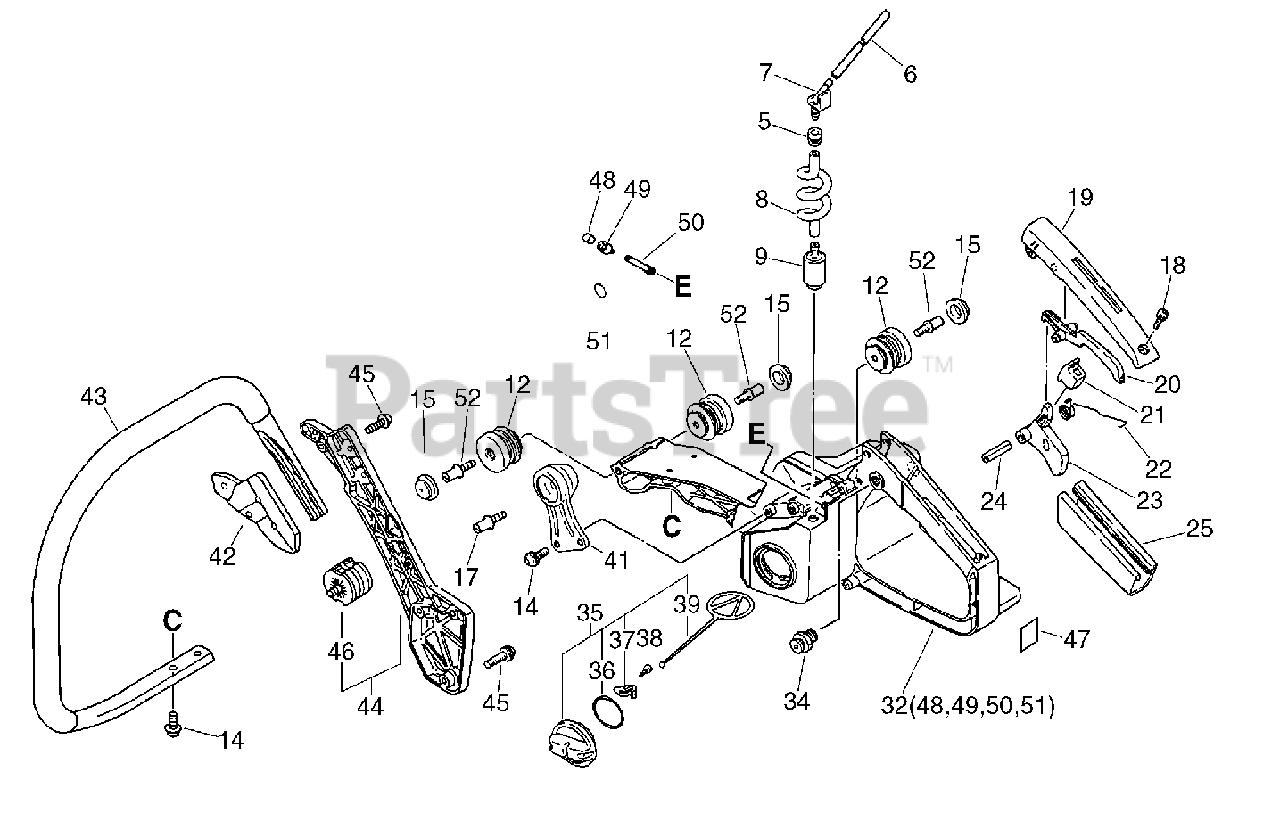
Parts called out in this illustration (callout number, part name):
5	GROMMET
6	PIPE - 3X6X100 -- BLACK
7	CONNECTOR, PIPE
8	PIPE - BLACK
9	FILTER, FUEL
12	CUSHION
14	SCREW - 5X14
15	CAP, CUSHION
18	SCREW - 4X14
19	COVER, HANDLE
20	LOCKOUT, THROTTLE
21	CUSHION, THROTTLE
22	SPRING, TRIGGER
23	TRIGGER, THROTTLE
24	PIN - SPRING -- 5X25
25	GRIP, HANDLE
32	HANDLE - REAR
34	LATCH, THROTTLE
35	CAP ASSY
36	O-RING - 29
37	RETAINER
38	SCREW - 3X8
39	CONNECTOR, CAP
42	BRACKET, HANDLE
43	HANDLE - FRONT
44	SUPPORTER,F.HNDL KIT
45	SCREW - 5X20
47	LABEL - STOP
48	VENT, FUEL TANK
49	COVER, VENT
50	PIPE - VENT
51	CLIP - 5.5
